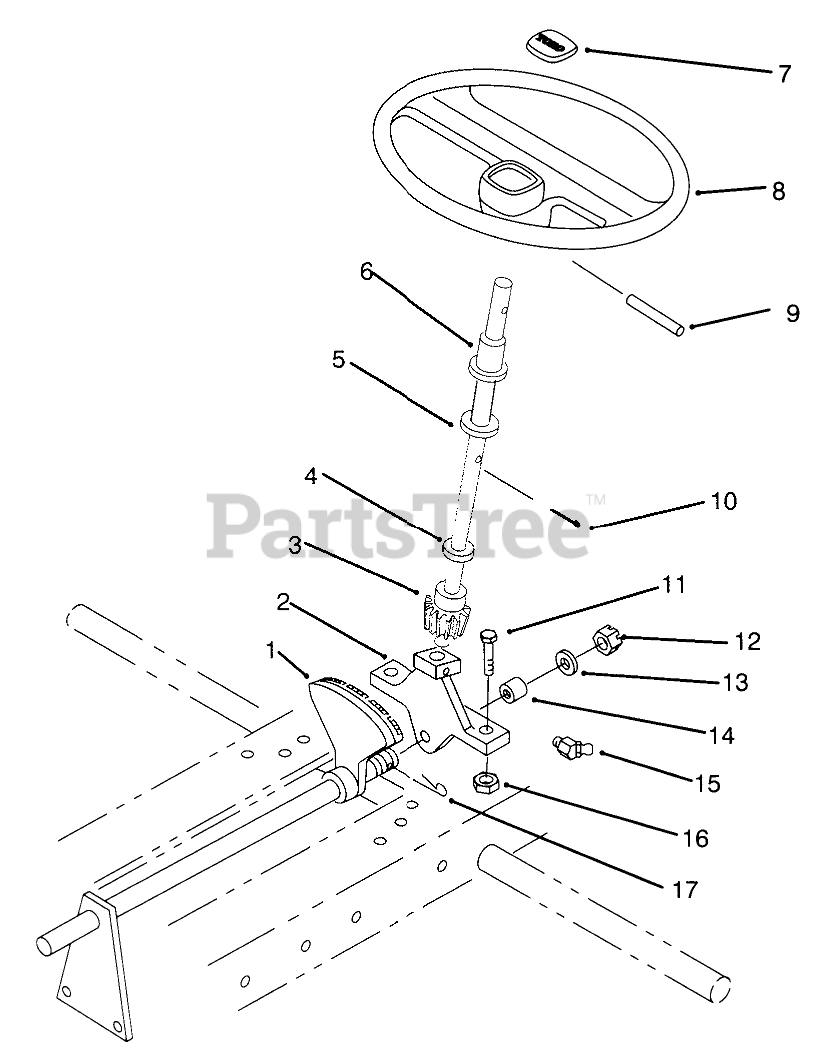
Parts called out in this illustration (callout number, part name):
1	Shaft
2	Support-Steering
3	STEERING SHAFT WA
4	O-RING
5	WASHER-SHIM
6	BEARING-FLANGED
7	STRG-WHL INSERT TORO
8	Wheel-Steering(Incl. Ref. #7)
9	PIN-ROLL
10	PIN-COTTER
11	SCREW-HH
12	NUT-HEX, SLOTTED
13	WASHER
14	BEARING-BRONZE
15	FITTING-GREASE
16	NUT-LOCK, NI
17	PIN-COTTER
